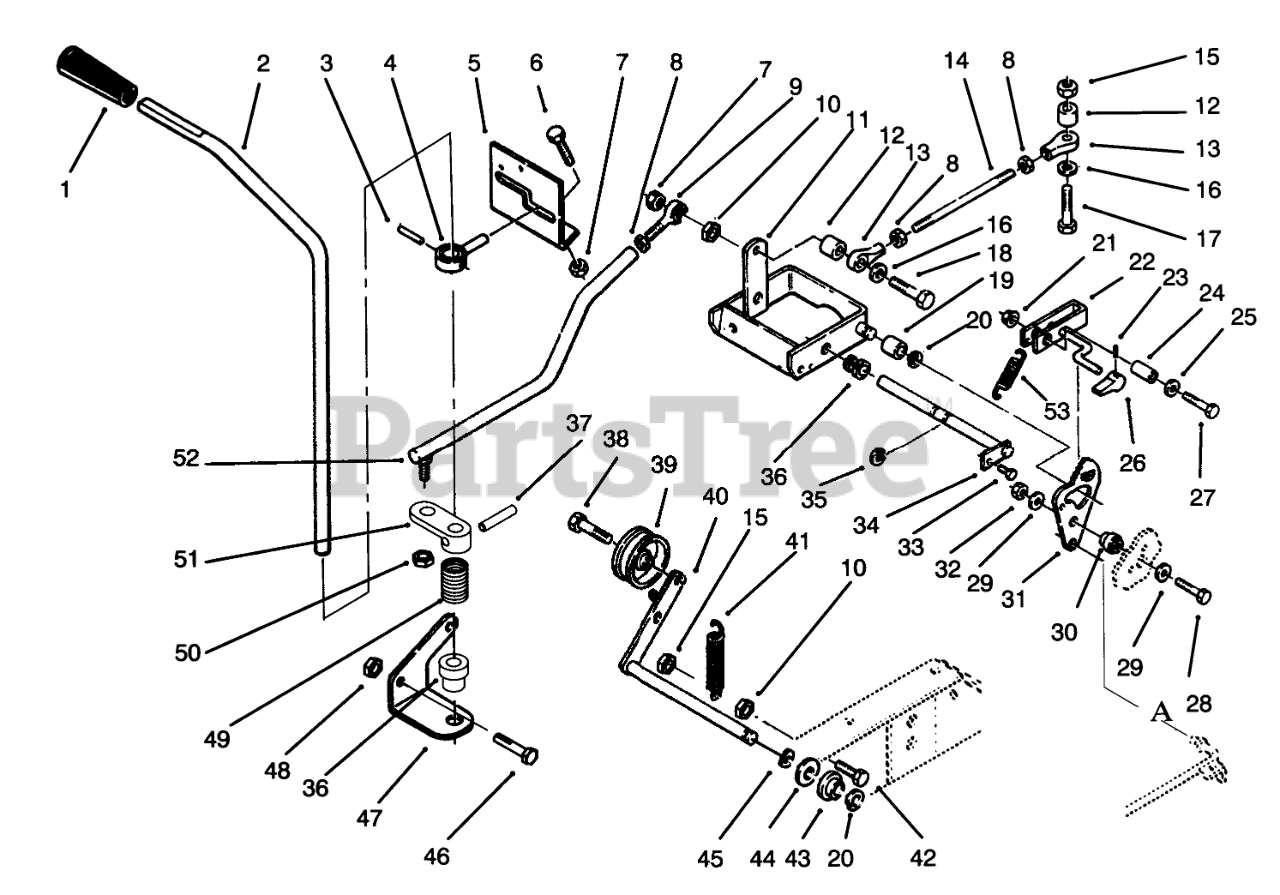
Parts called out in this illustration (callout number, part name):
1	Knob-Motion Control
2	ROD-MOTION CONTROL
3	SPIROL PIN 7/32X7/8
4	GUIDE-CONTROL
5	Bracket-Control
6	SCREW-HH
7	NUT-LOCK, NI
8	NUT-JAM
9	ROD END, 1/4-28
10	NUT-HEX
11	Cam Comtrol
12	Spacer
13	ASSY ROD END
14	ROD-CONTROL
15	NUT-LOCK
16	WASHER-FLAT
17	SCREW-HH
18	HHCS 1/4X2.25 FULL T
19	BEARING-CAM RETURN
20	RING-RETAINING, EXTERNAL
21	LOCKNUT-FLANGE
22	Lever-Parking Brake
23	PIN-SPIROL 3/32X5/8
24	SPACER
25	WASHER-SPACER
26	KNOB-PARKING BRAKE
27	SCREW-HH
28	SCREW-HH
29	WASHER-FLAT
30	Spacer
31	Cam Plate
32	NUT-LOCK, NI
33	SCREW
34	ASSY-ROD CAM PIVOT
35	RING-RETAINING, EXTERNAL
36	NYLINER BUSHING
37	PIN-SPECIAL
38	SCREW-HH
39	PULLEY-IDLER
40	WLDMT-IDLER ARM
41	SPRING-EXTENSION
42	SCREW-HH
43	BUSHING-FLANGED
44	SHIM-WASHER
45	CURVED-SPRING WASHER
46	SCREW-HH
47	Bracket-Control
48	NUT-LOCK, NI
49	SPRING-COMPRESSION
50	NUT-LOCK
51	ARM-CONTROL
52	ASSY-ROD & BALL JOINT
53	EXTENSION-SPRING
